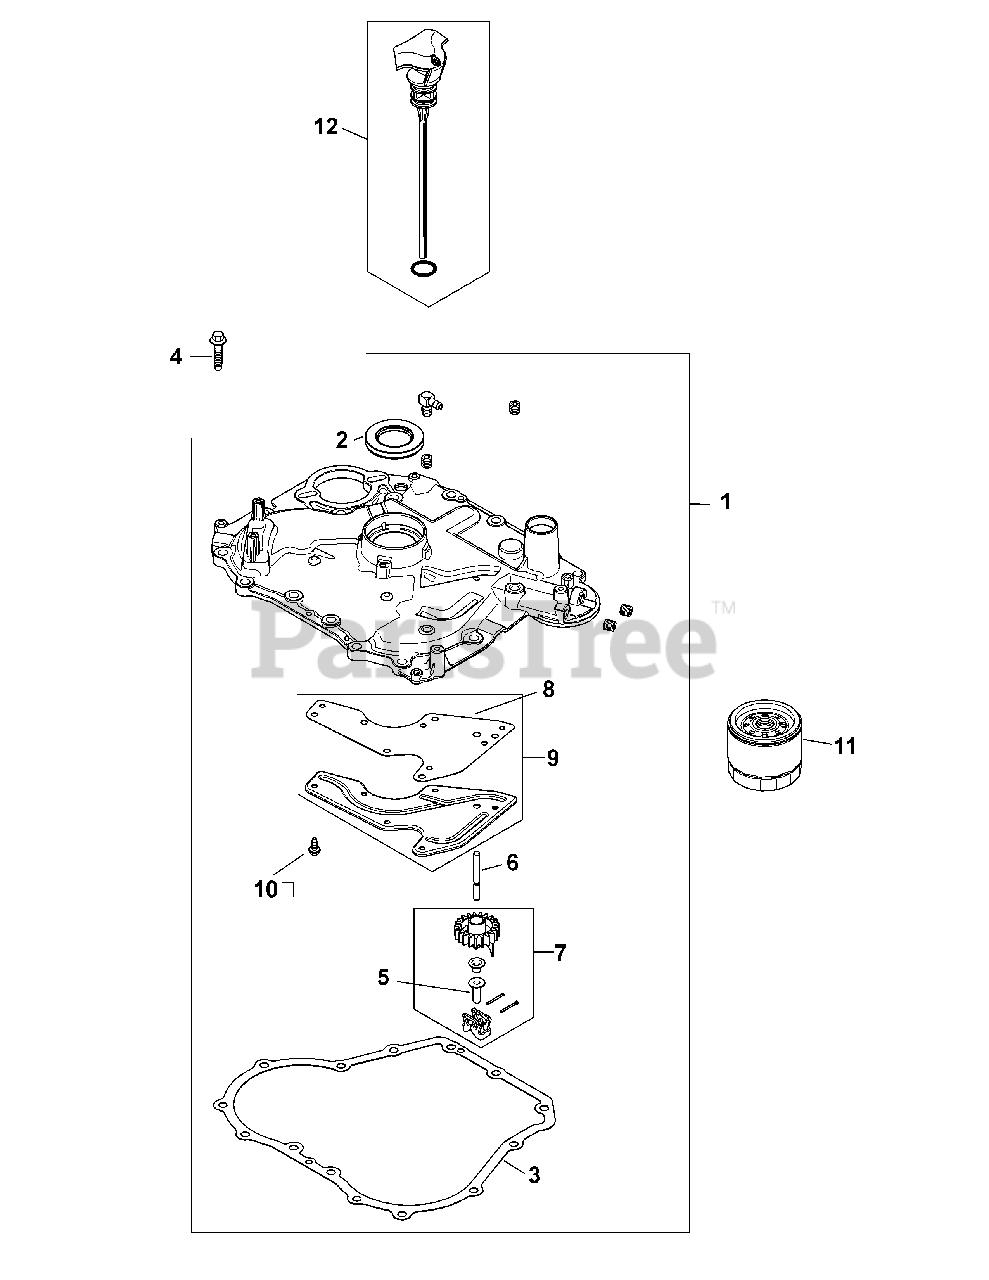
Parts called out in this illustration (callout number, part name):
1	Closure Plate Assembly
3	Closure Plate Gasket
4	Hex Flange Screw, 1/2
5	Governor Regulating Pin
6	Governor Cross Shaft
7	Governor Gear Assembly
8	Oil Passage Gasket
9	Oil Passage Cover Kit (Includes 7)
10	Flg. Thd. Frm. Screw, M5 X 0.8 X 13
12	Dipstick Assembly Blade
